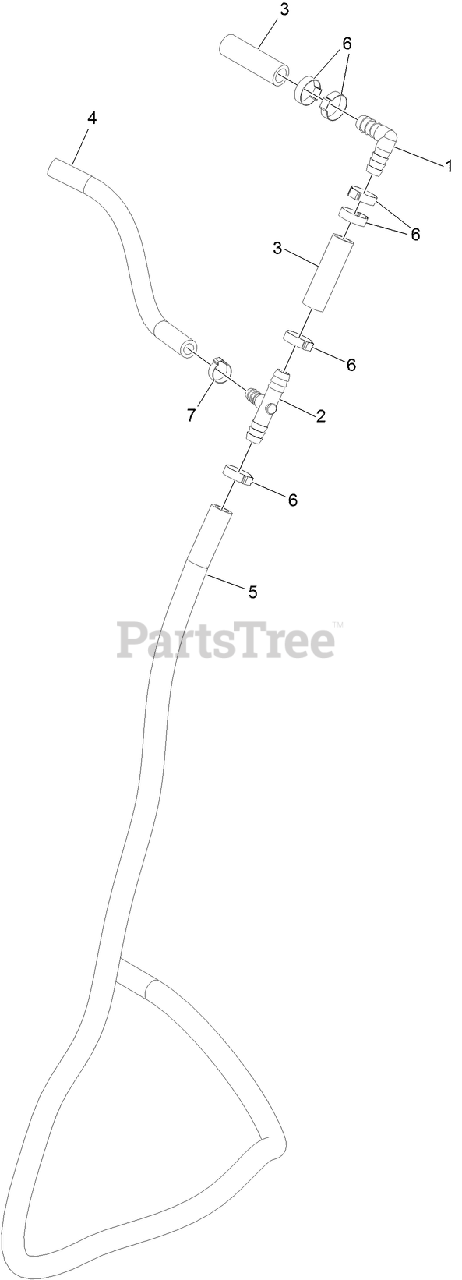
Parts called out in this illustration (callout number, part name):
1	FITTING-ELBOW-90
2	CONNECTOR-TEE
3	HOSE-WATER
4	HOSE-WATER
5	HOSE-WATER
